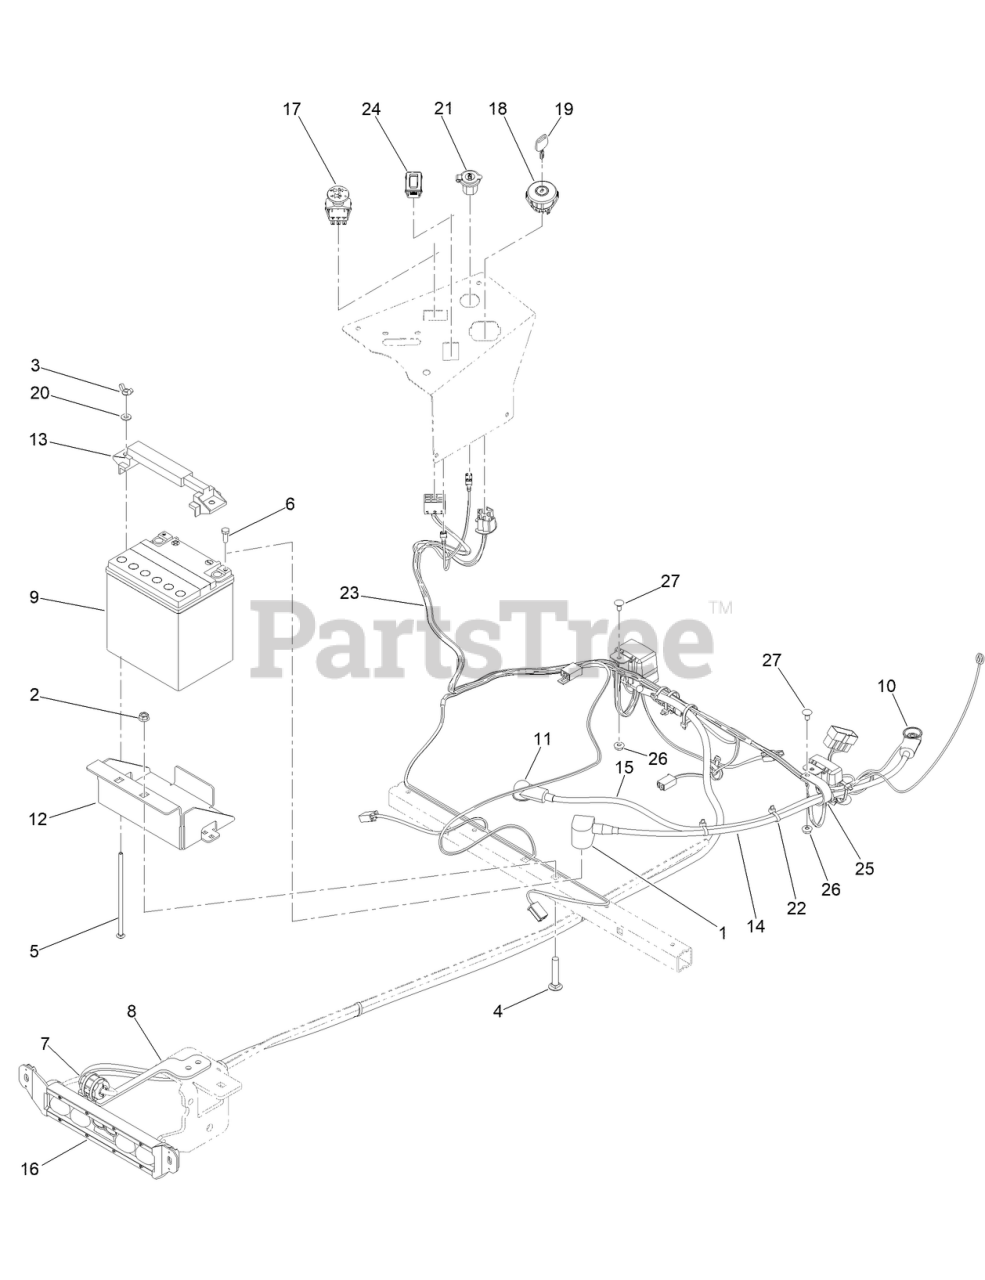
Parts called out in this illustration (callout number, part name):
1	INSULATOR-BATTERY
2	3/8-16 HEX FLANGE NUT W/SERR ZINC YELLOW
3	NUT-WING
4	SCREW-CARR
5	1/4IN-20X8IN GR5 CARRIAGE BOLT
6	SCREW-HH
7	FAIR-RITE ROUND CABLE SNAP-IT SIZE B
8	FAIR-RITE BRACKET PAINTED
9	BATTERY - ETX30LA - 400CCA
10	3.15 LGTH STRAIGHT INSUL TERM COVER RED
11	STRAIGHT INSULATING TERMINAL COVER
12	MWR BATTERY BOX
13	BATTERY HOLD DOWN
14	MWR POSITIVE BATTERY CABLE 25IN
15	MWR NEGATIVE CABLE 28
16	SPLIT BEAM W/NON-LIGHTD HELMET LIGHT BAR
17	PTO SWITCH
18	IGNITION SWITCH
19	2023 MWR KEY
20	WASHER-FLAT
21	12 VOLT AUXILLIARY PLUG
22	TIE-CABLE
23	HARNESS-WIRE
24	HOUR METER
25	1-1/4IN CUSHIONED LOOP CLAMP BLACK
26	1/4-20 HEX FLANGE NUT
27	SCREW-CARR
